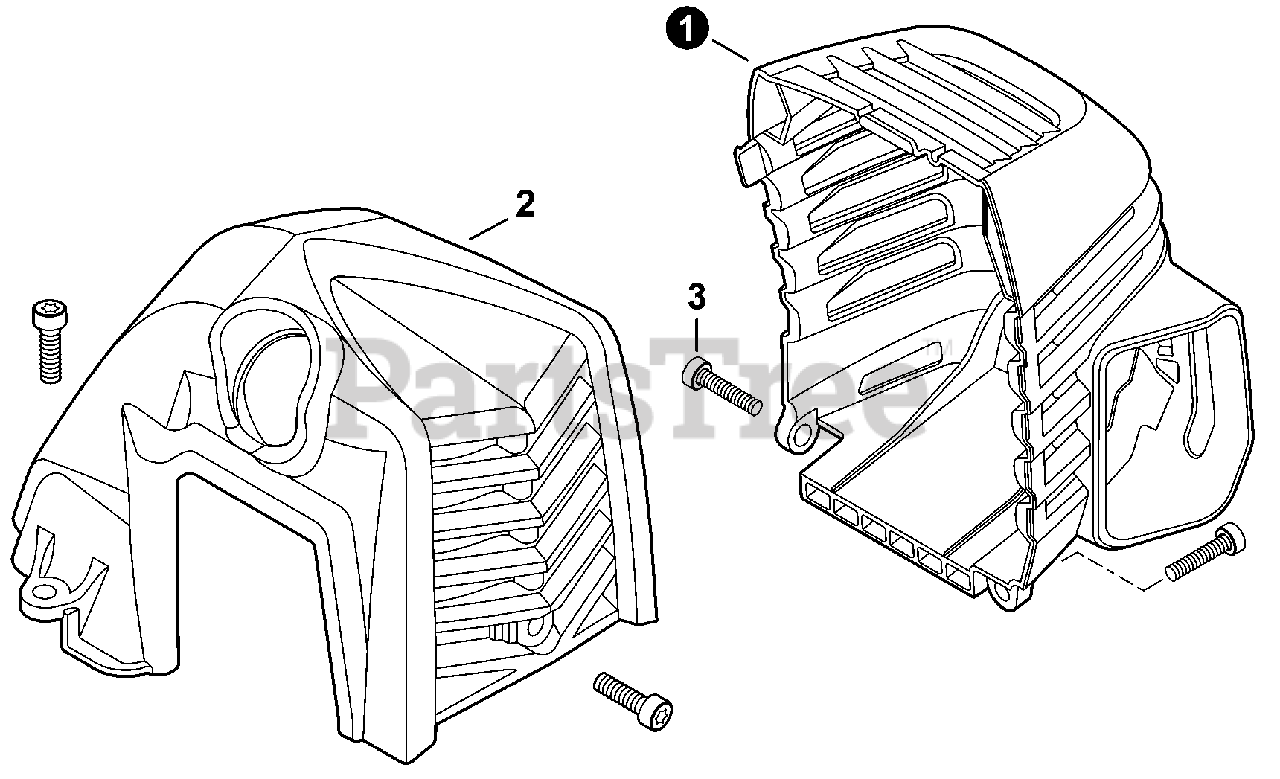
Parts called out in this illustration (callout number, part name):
1	COVER, MUFFLER
2	COVER, ENGINE
3	BOLT, TORX 5×12
